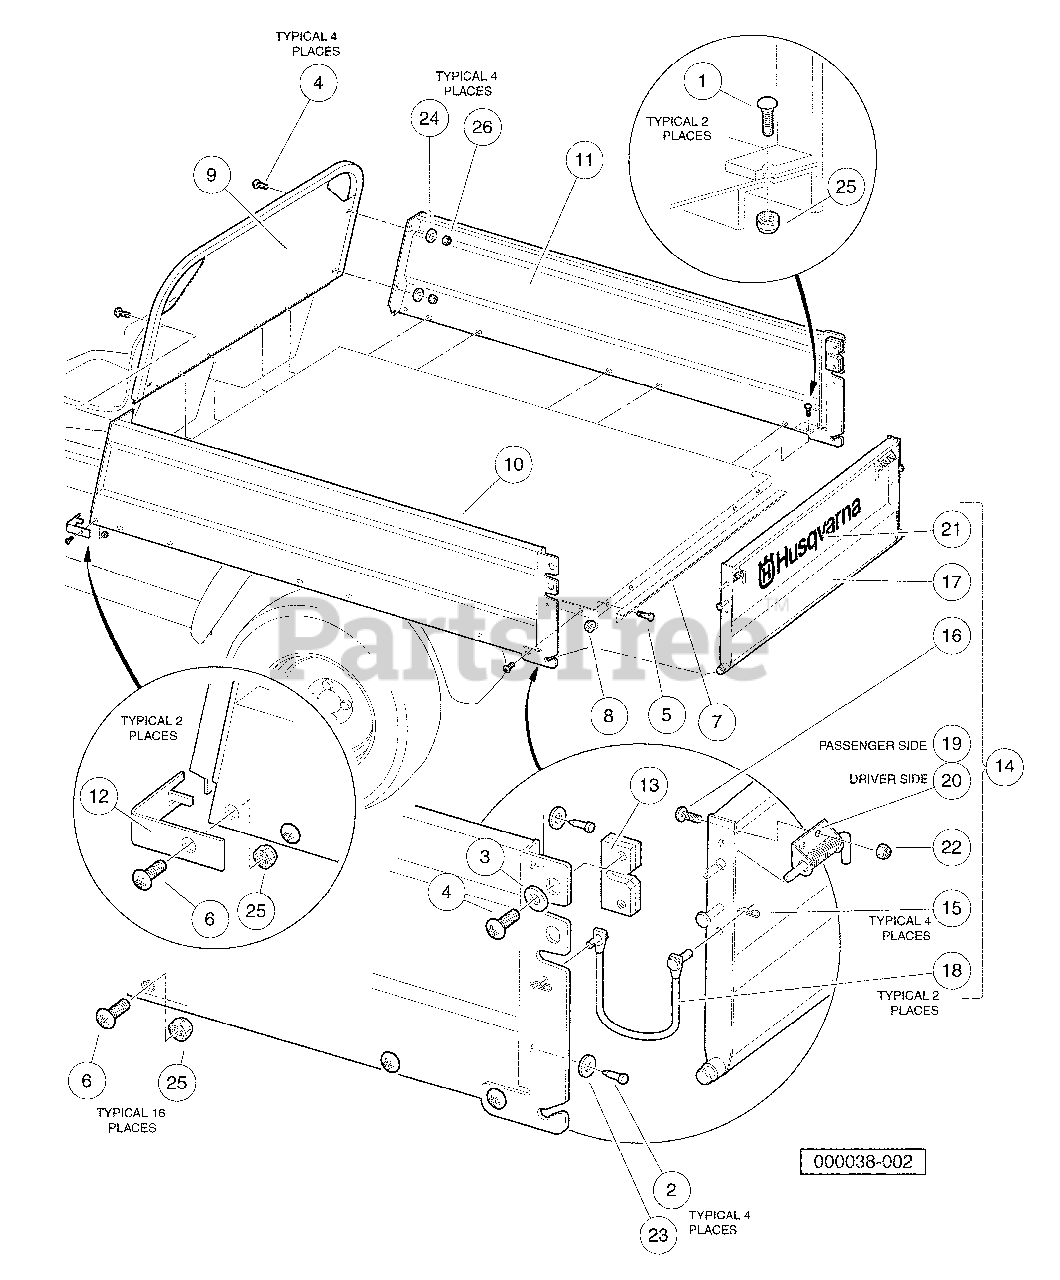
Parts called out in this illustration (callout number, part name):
1	Bolt, Carriage, 5/16-18 X 1.00
2	Bumper, Rubber
3	Washer, 1/4" Type B Flat
4	Screw, 1/4-20 X 0.75 Torx Truss-Head
5	Stud, Self-Clinching Flush Head
6	Screw, 5/16-18 X 0.88 Torx Truss-Head
7	Box Bed Tailgate Angle
8	Locknut, 5/16-18 Hex Flange
9	Front Panel Weldment
10	Left Panel Weldment
11	Right Panel Weldment
12	Front Corner Cap
13	Slam Latch
14	Assembly, Tailgate
15	Hair Pin Clip
16	Screw, 1/4-20 X 0.75 Torx Truss-Head
17	Tailgate, Weldment
18	Tether Assembly
19	Spring Latch Left
20	Spring Latch Right
21	Decal, Husqvarna, Tailgate
22	Locknut, 1/4-20 Nylon Insert
23	Washer, Rubber, 3/8
24	Washer, 1/4 Type A Narrow Flat
25	Locknut, 5/16-18 Nylon Insert
26	Locknut, 1/4-20 Nylon Insert
